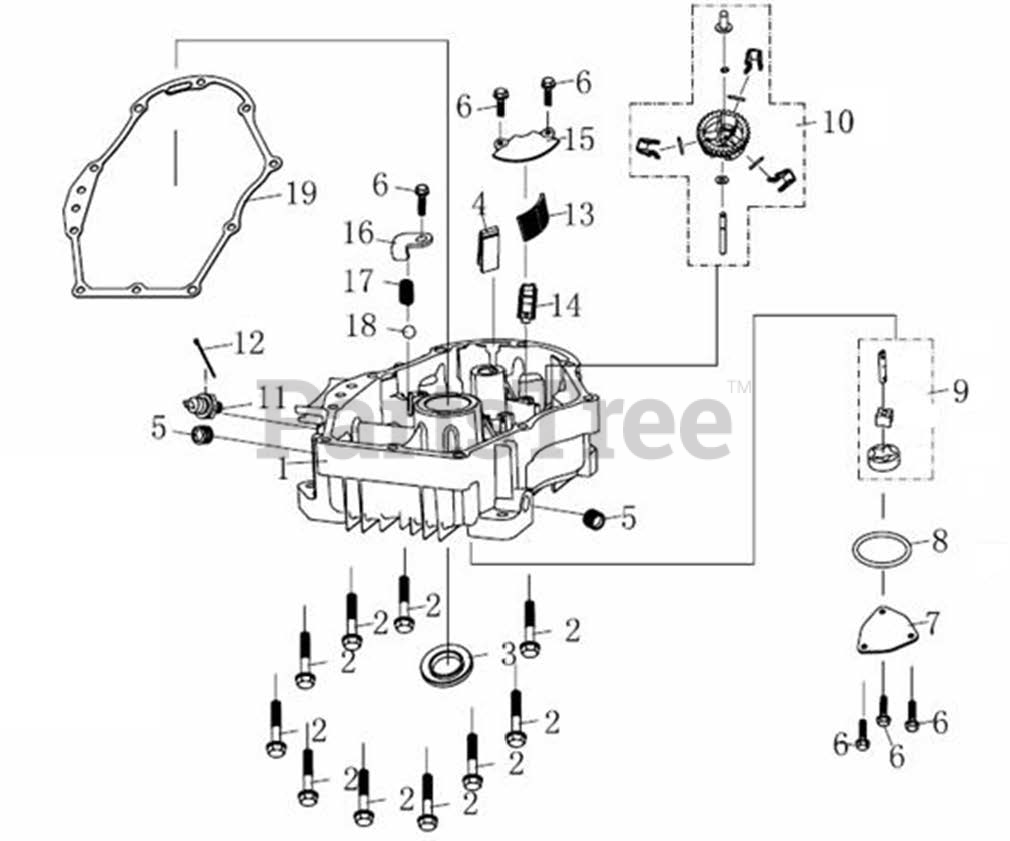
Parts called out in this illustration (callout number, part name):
1	CRANKCASE COVER
2	HEXAGON BOLT WITH FLANGE
3	OIL SEAL
4	ENGINE OIL RETURN BLOCK
5	SEALING PLUG SCREW
6	BOLT, FLANGE
7	OIL PUMP COVER
8	SEAL RING
9	COMPONENTS OF OIL PUMP
10	COMPONENTS OF GOVERNOR GEAR
11	OIL LEVEL ALARM
13	ENGINE OIL STRAINER
14	PRESSING PLATE FOR OIL GROOVE
15	COVER,OIL STRAINER
16	PRESSING PLATE FOR OIL GROOVE
17	COMPRESSION SPRING
18	STEEL BALL
19	CRANKCASE COVER GASKET
